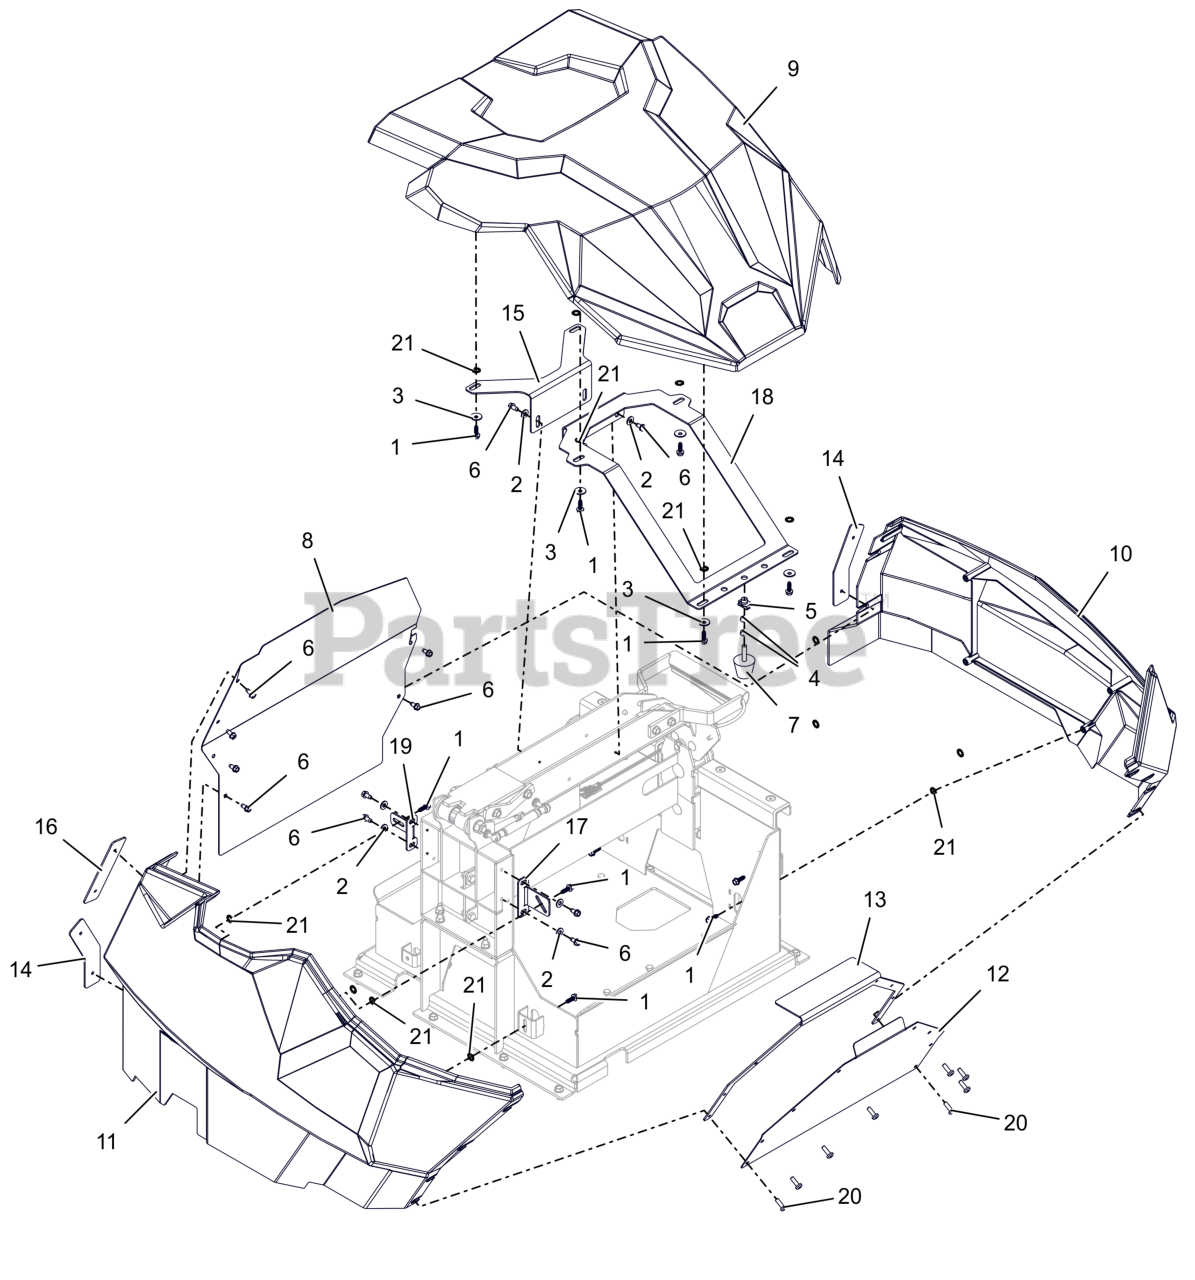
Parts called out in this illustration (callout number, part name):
1	SCR, PLASTITE .25-10X.75 ZCC
2	WSHR,FLT .281X.625X.065 ZCC
3	WSHR,BLVL-.250X.815X.061 ZFS
4	NUT-JAM .312-18 G2 ZCC
5	NUT-CLIP RETAINER 5/16-18X.56
6	SCR-TAP .25-20X.50 HWH ZCC
7	BUMPER, STUD MOUNTED CONE SHAPED
8	BRKT, FENDER - REAR (BLACK)
9	HOOD, BATTERY CAPTURE
10	FENDER, BATTERY CAPTURE - LH
11	FENDER, BATTERY CAPTURE - RH
12	BRKT, FENDER - FRONT (ORANGE)
13	PLATE, BACK - FRONT (BLACK)
14	PLATE, BACK REAR LH (BLACK)
15	SUPPORT, HOOD (BLACK)
16	PLATE, BACK - REAR UPPER (BLACK)
17	SUPPORT, FENDER (BLACK)
18	SUPPORT, HOOD (BLACK)
19	SUPPORT, FENDER (BLACK)
20	SCR-TAP 1/4-20X3/4 LPAN TL BZ
21	WSHR,LK-EXT .326X.599X.031 ZCC
